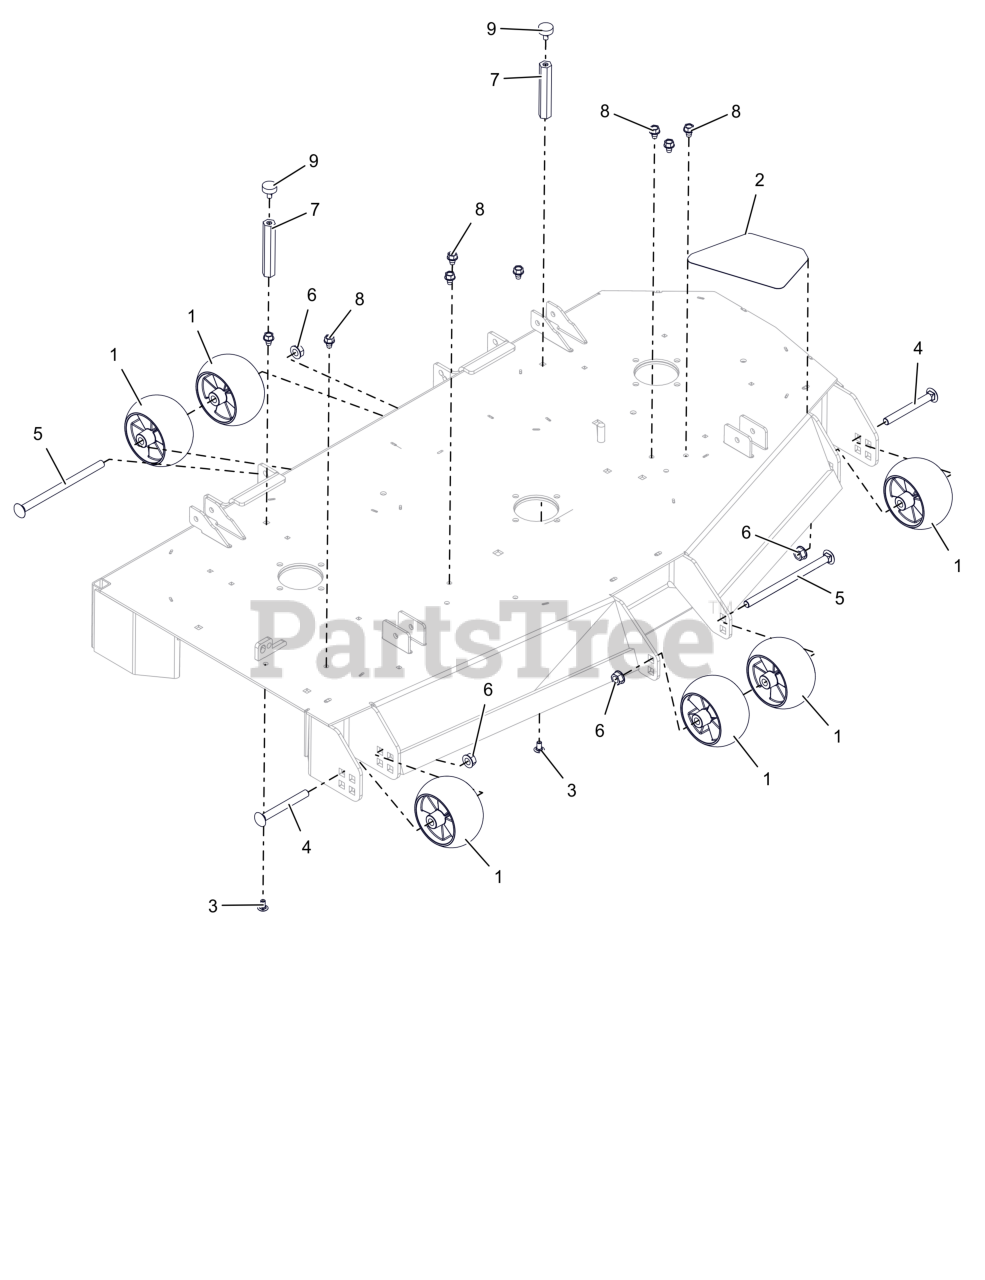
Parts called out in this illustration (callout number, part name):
1	WHEEL, ANTI SCALP - 5X3 CTR W/RIBS
2	GRIP, STEP ANTI SKID
3	BTL,RHSSN .313-18 X 0.625 G5 ZCC
4	BLT,RHNS .50-13X4.50 G5 ZCC NS
5	BLT,RHSN .50-13X8.00 G5 ZCC NS
6	NUT-LK-CTR-FLG .500-13 GG ZCC
7	NUT, COUPLING .312-18 X 4.295
8	SCR,TAP .375-16X.50 HWH TR ZCC
9	BUMPER, RUBBER
